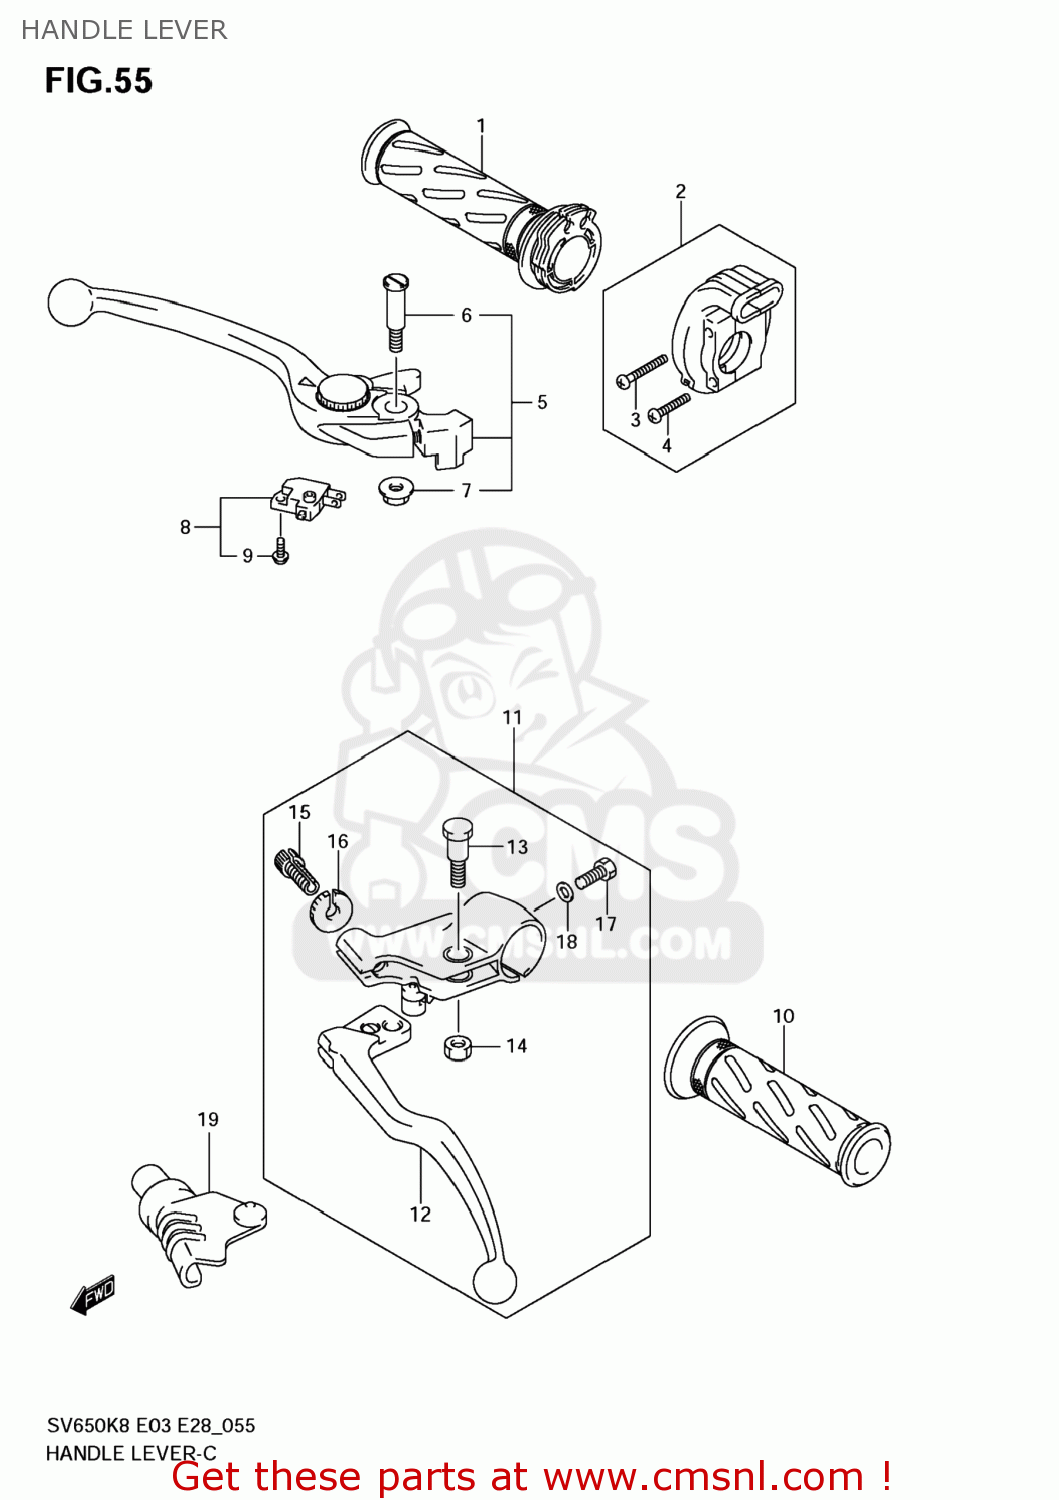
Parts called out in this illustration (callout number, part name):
1	GRIP,THROTTLE
2	CASE ASSY,THROTTLE
3	SCREW(5X25)
4	SCREW
5	LEVER ASSY,BRA
6	BOLT,LEVER
7	NUT
8	SWITCH ASSY,ST
9	SCREW
10	GRIP,LEFT
11	LEVER ASSY,CLUTCH
12	LEVER,CLUTCH
13	BOLT,LEVER SET
14	NUT
15	ADJUSTER,CABLE
16	NUT,CABLE ADJUSTER
17	BOLT
18	WASHER
19	COVER,CLUTCH LEVER
